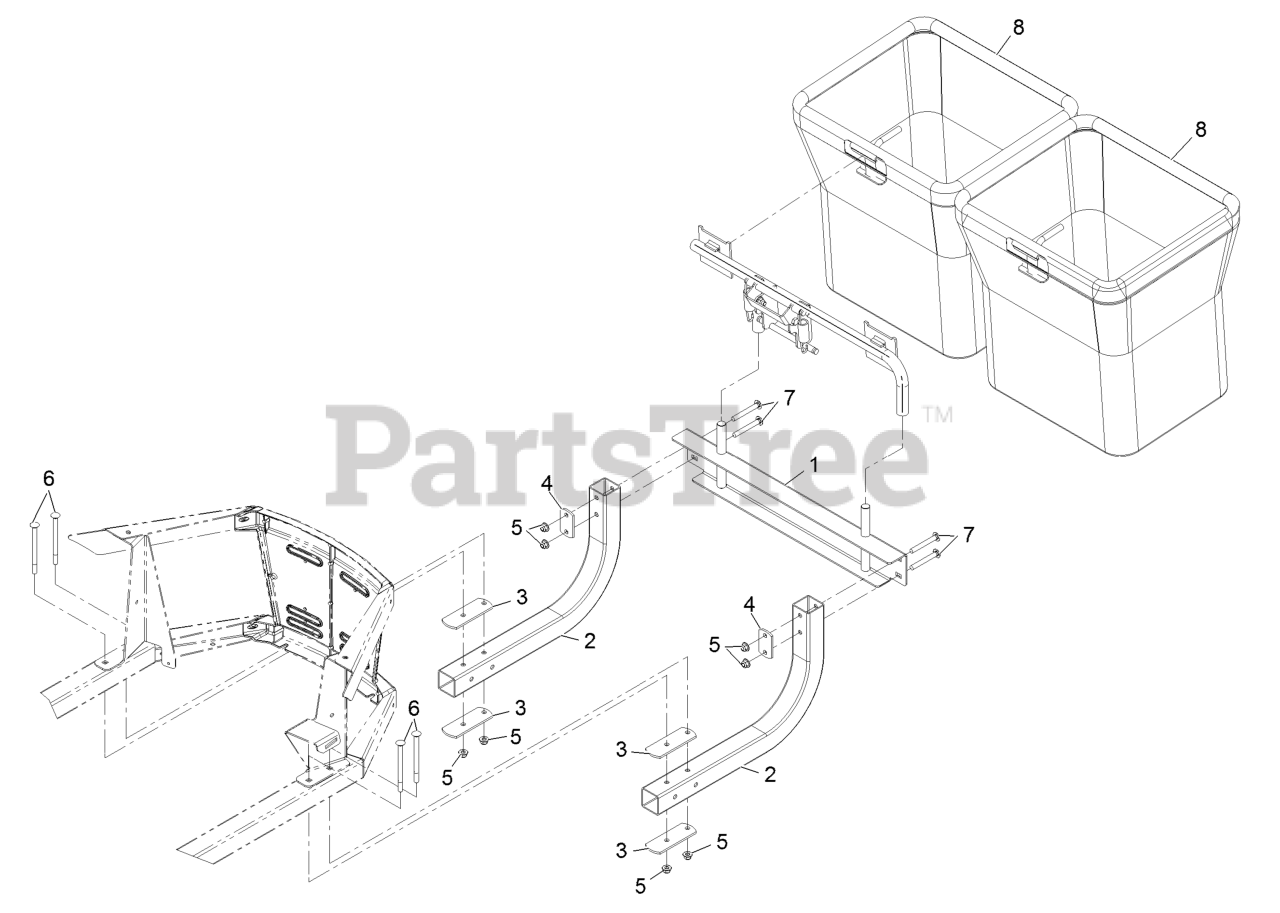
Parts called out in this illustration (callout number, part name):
1	BAGGER HITCH ASM
2	TUBE-HITCH, BAGGER
3	PLATE-STIFFENER
4	PLATE-STIFFENER
5	NUT-HF, NI
6	BOLT-CARR
7	SCREW-CARR
8	ASM,BAG
